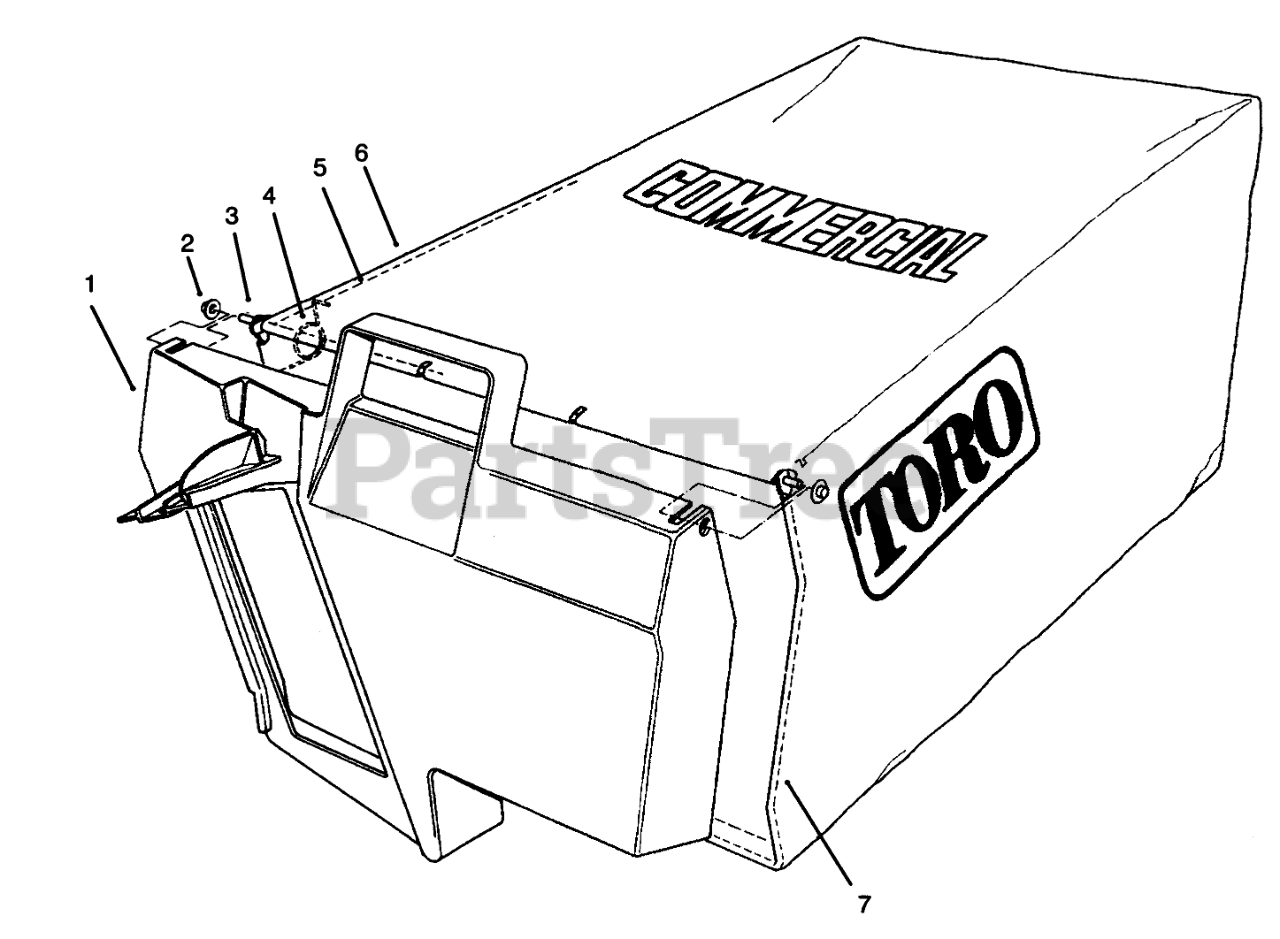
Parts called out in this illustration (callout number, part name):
1	DOOR-BAG, GRASS
2	NUT-PUSH
3	HINGE-DOOR, BAG
4	SPRING
5	FRAME-BAG, UPPER
6	Bag
7	FRAME-BAG
